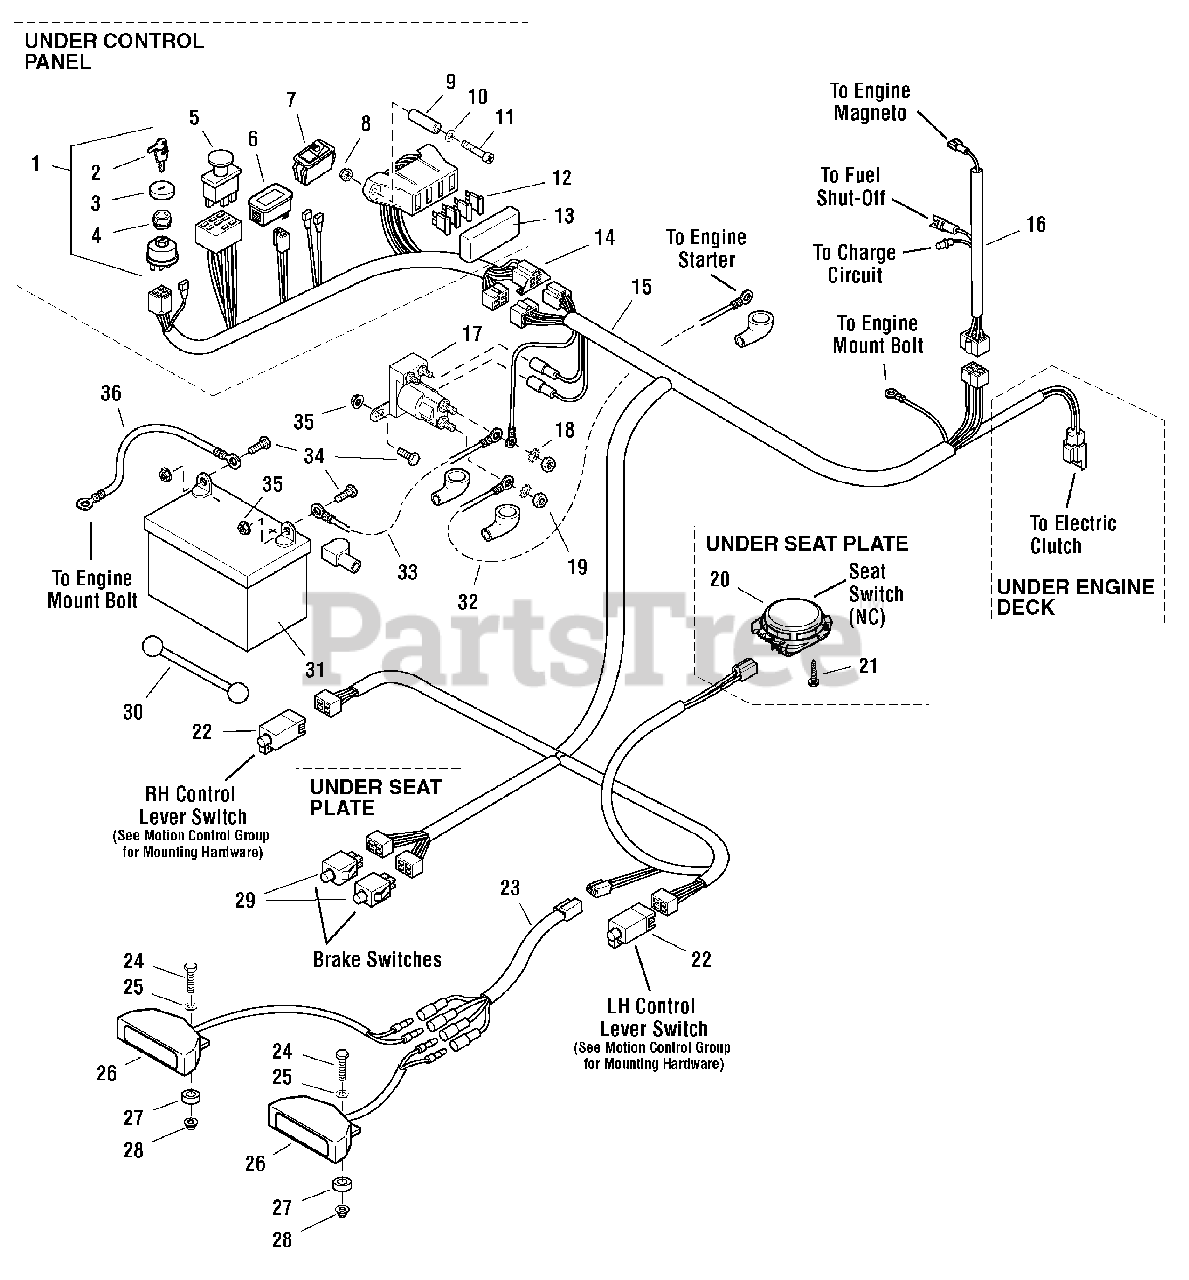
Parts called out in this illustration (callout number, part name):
1	SWITCH, Ignition, Complete (Includes Ref No. 2 - 4)
2	KEY, Ignition Molded (Set of 2)
4	PLASTIC NUT
5	SWITCH, PTO
7	HEADLIGHT SWITCH
8	NUT, #10-24 Hex Nylon Lock
9	SPACER, .20 x .38 x 1.25
10	WASHER, #10 SAE
11	SCREW, #10-24 x 2"
13	FUSE BLOCK COVER
14	HARNESS ASSEMBLY, Control Panel
15	HARNESS ASSEMBLY, Main
16	ENGINE HARNESS
17	SOLENOID
18	WASHER, Light Lock, 5/16
19	NUT, Hex Jam, 5/16-24
20	SWITCH, Seat, Gray, NC
21	BOLT, Hex Washer Head PLASTITE, 1/4 X 1/2
22	SWITCH, PLUNGER, N.O./N.C.
23	HEADLIGHT HARNESS
24	BOLT, 1/4-20 X 1-1/4
25	WASHER, 1/4 SAE (5025154)
26	HEADLIGHT
27	SPACER, .39 X .75 X .38
28	NUT, 1/4-20 HEX NYLOCK FLANGE (5025391)
29	SWITCH, DP NO/NC SNAP-IN
30	STRAP, BATTERY, 14 LONG, Rubber
31	BATTERY, Lawn & Garden, 12V (BCIU1, 340 CCA)
32	POSITIVE (+) BATTERY CABLE, 22"
33	POSITIVE (+) BATTERY CABLE, 22"
34	BOLT, 1/4-20 x 3/4
35	NUT, 1/4-20 Hex Serrated Flange
36	CABLE, Ground
